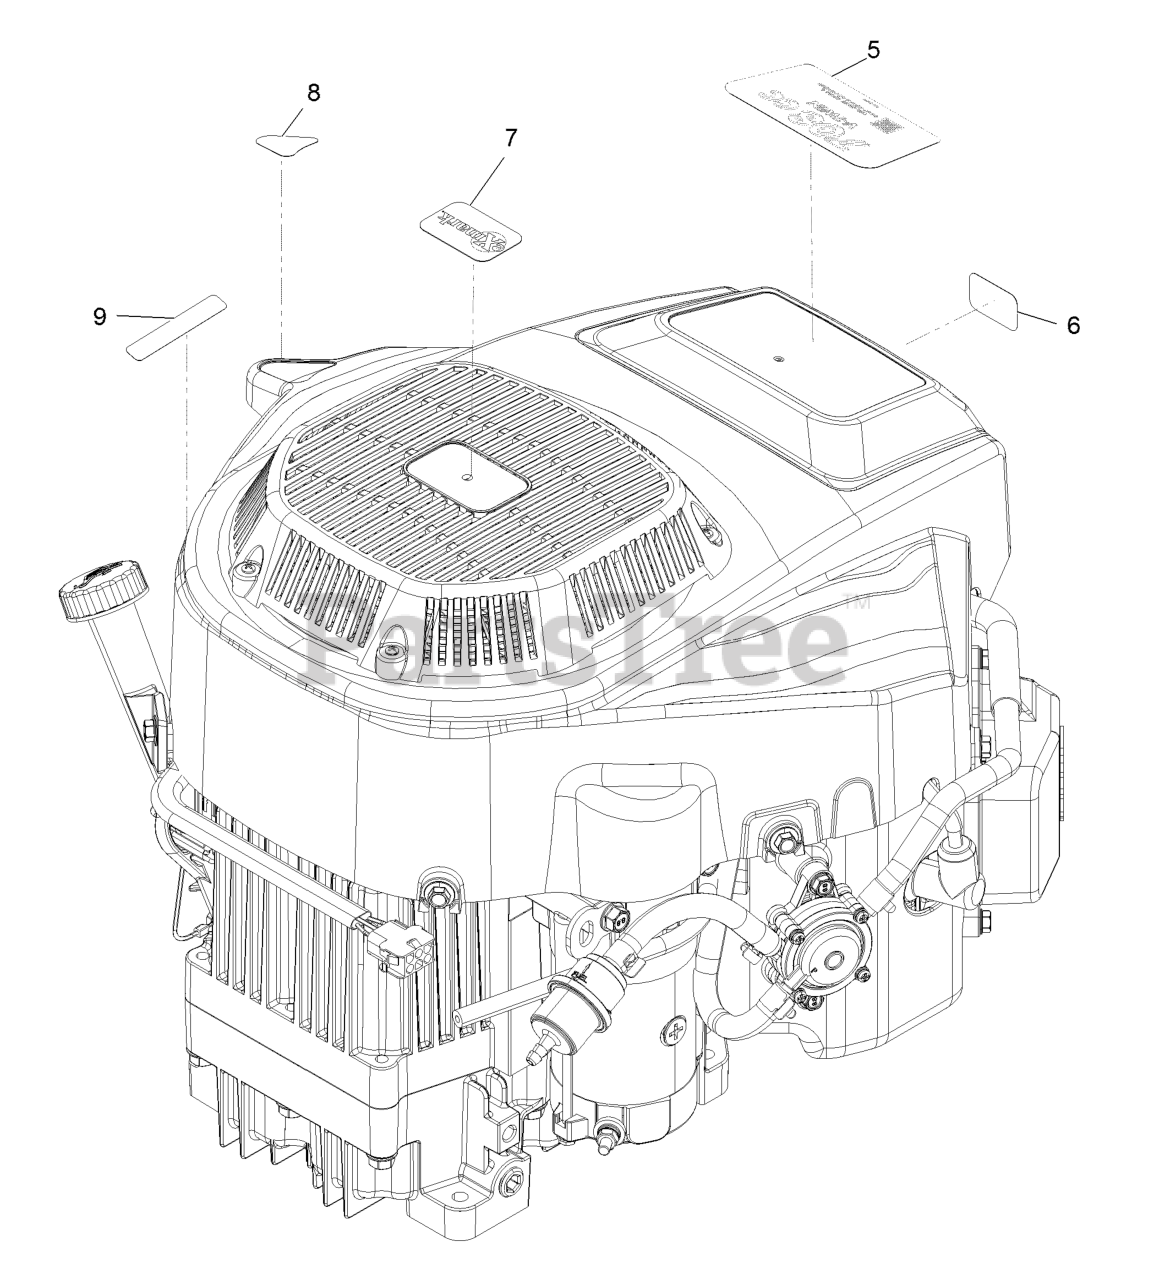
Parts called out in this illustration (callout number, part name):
5	DECAL-ENGINE DISPLACEMENT
6	PLACARD-INTAKE, EXMARK
8	DECAL-DRAIN, OIL
9	DECAL-SHUTDOWN
